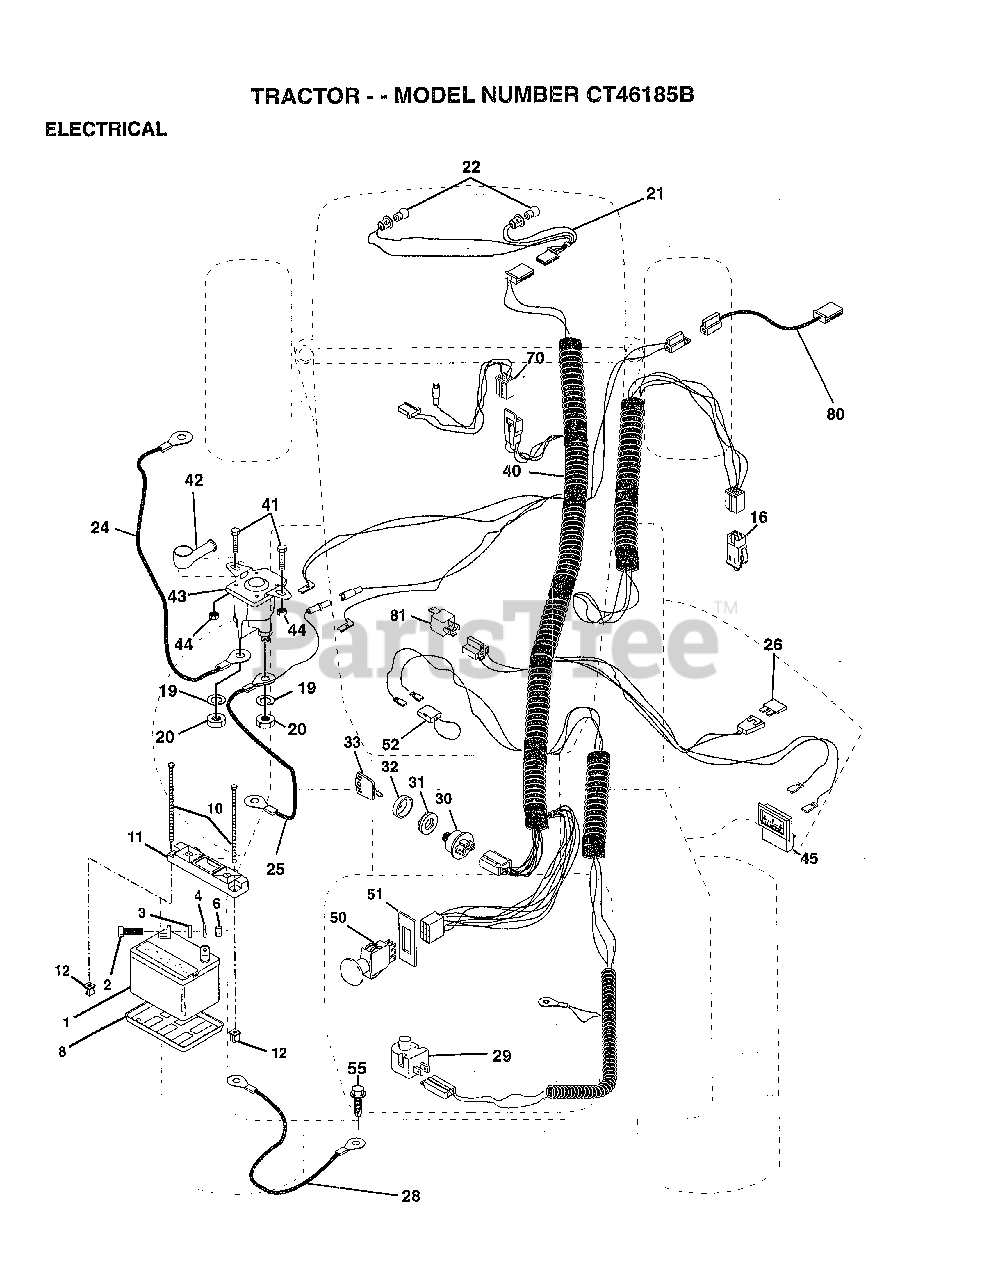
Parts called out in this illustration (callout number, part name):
2	BOLT LT
3	WASHER
4	LOCKWASHER
8	"TRAY T, BATTERY"
11	HOLDDOWN BATTERY
16	SWITCH INTERLOCK
20	NUT
21	"HARNESS,LIGHT SOC"
22	HEADLAMP BULB
24	"CABLE T, BATTERY"
25	CABLE.6GA.22W/16W
26	FUSE HYT
28	CABLE.GRND.6GA.21
29	SWITCH.PLUNGER
30	SWITCH IGN 4POS
31	NUT IGNITION
32	COVER KEY SWITCH
33	KEY
40	"HARNESS.IGN.AM,HM"
41	BOLT HXHD FIN
44	NUT HXKEP 1/4X20
50	PTO SWITCH.BLK
51	RING RETAIN PTO
52	PROTECTION LOOP
70	HARNESS ENG DUAL
80	HARNESS.CLUT.EVX.
81	RELAY ASSY T
